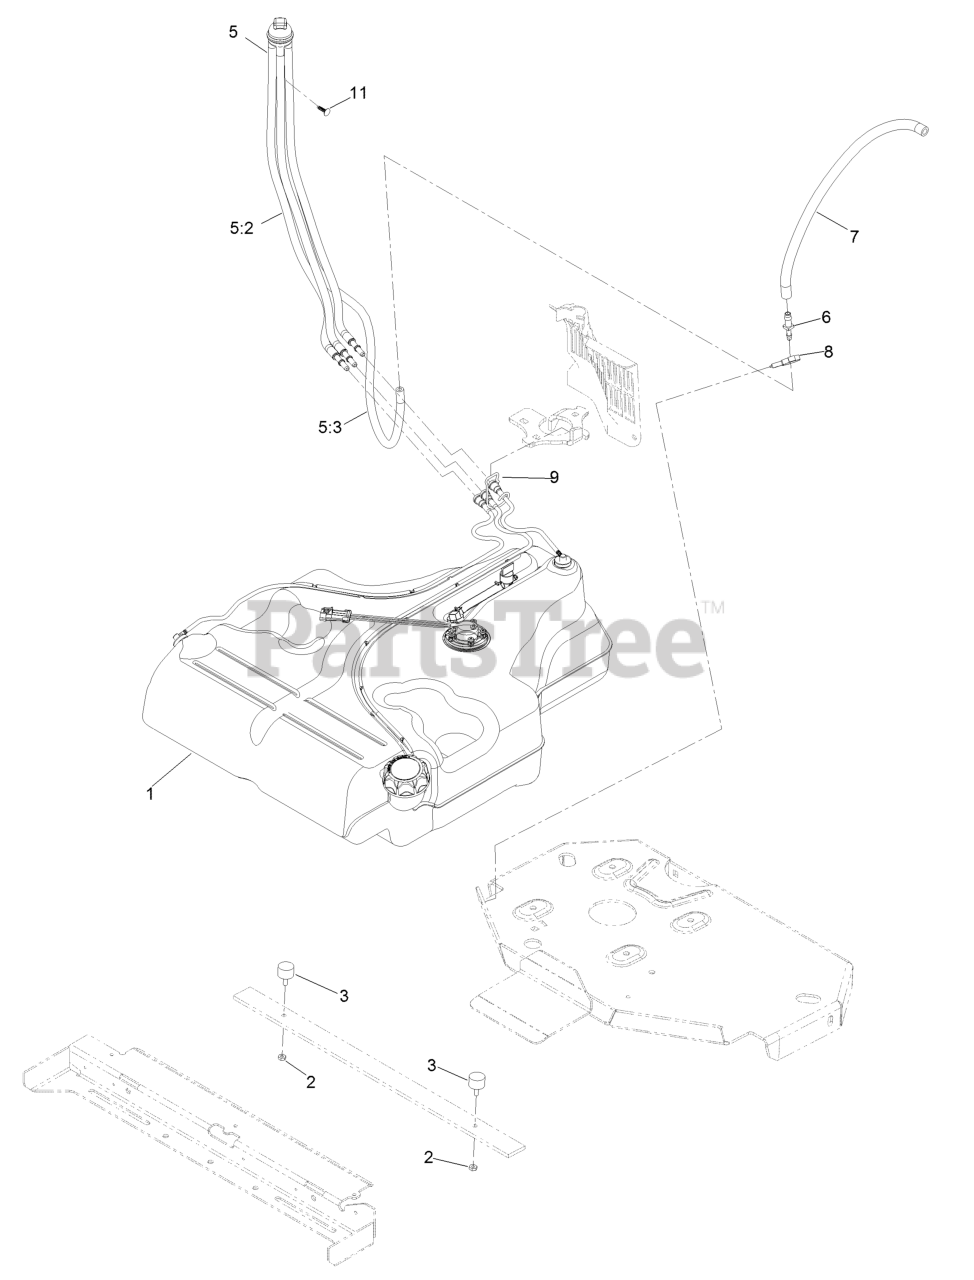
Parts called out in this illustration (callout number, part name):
1	Fuel Tank ASM
2	Nut-Jam
5	Fuel Manifold Vent ASM
5:2	Hose-Fuel
5:3	Hose-Fuel
6	Fitting-Straight
7	Hose-Fuel
8	Clamp-Hose
9	Retainer-Line, Vapor
11	Plug-Plastic
